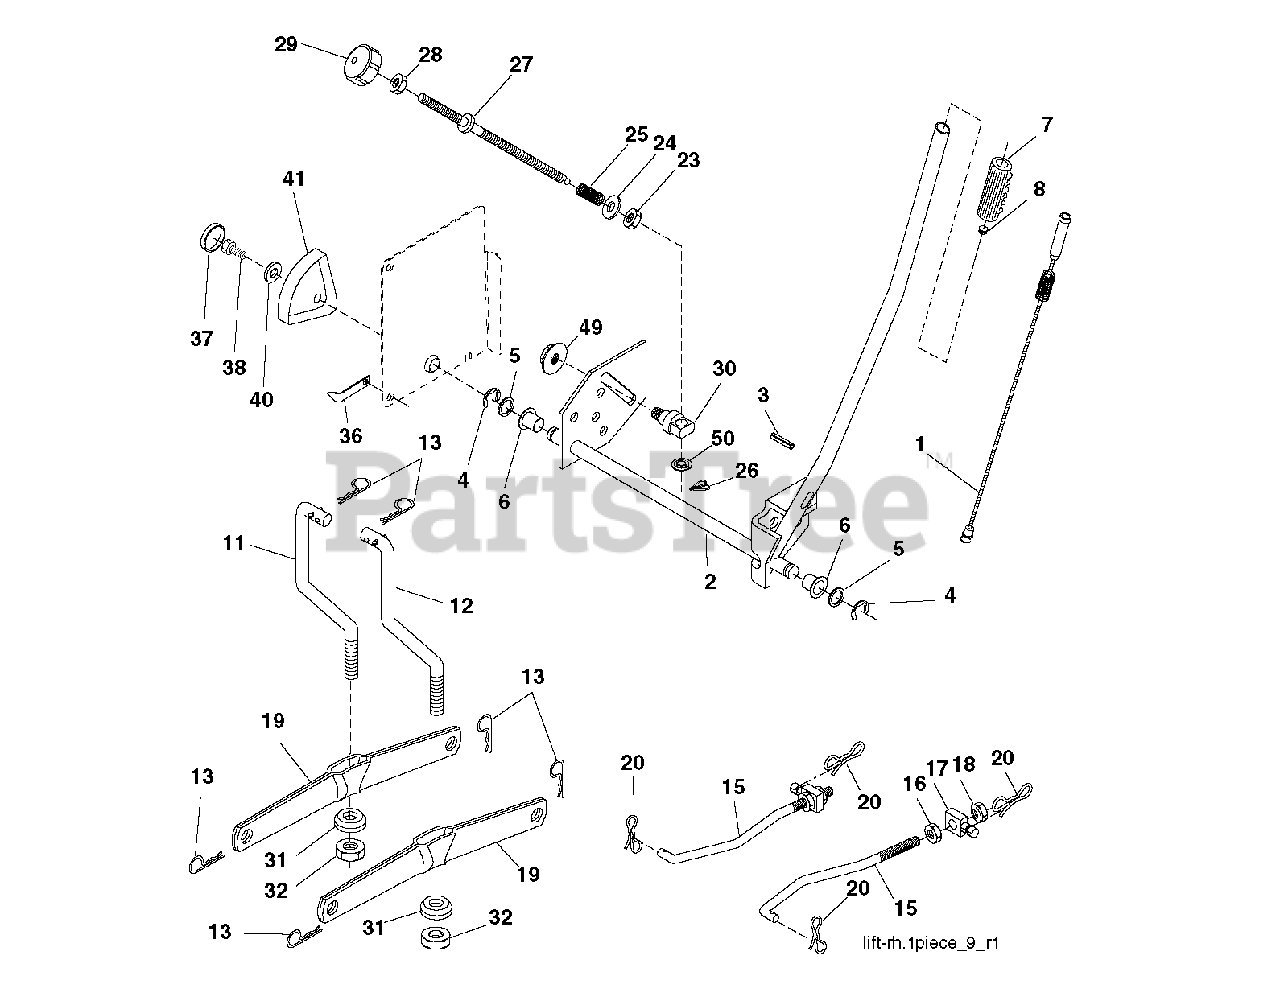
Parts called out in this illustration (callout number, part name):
1	PLUNGER.ASM.LIFT.LVR.BLK.17.32
2	SHAFT ASM R HANDLE
3	PIN GROOVE
4	RETAINING RING LT
6	BEARING.NYLON
7	GRIP HANDLE
8	PLUNGER BUT KIT
11	LINK LIFT LH
12	LINK LIFT RH
13	RETAINER-SPRNG RB
15	LINK.SUSPENSION.FRONT
16	NUT
18	NUT
19	ARM.REAR.SUSPENSION
20	PIN.COTTER.7/16.BOW TI
25	SPRING**
26	RETAINER CLIP
27	ROD ADJ LIFT
28	NUT
29	KNOB INF 3/8-16
31	BEARING.PIVOT.LIFT
32	NUT CROWNLOCK 3/8-24
36	POINTER, HEIGHT INDICATOR
37	PLUG,HOLE
38	SCREW 5/16-18X1
41	HEIGHT INDICATOR
49	NUT
50	NUT PUSH M
